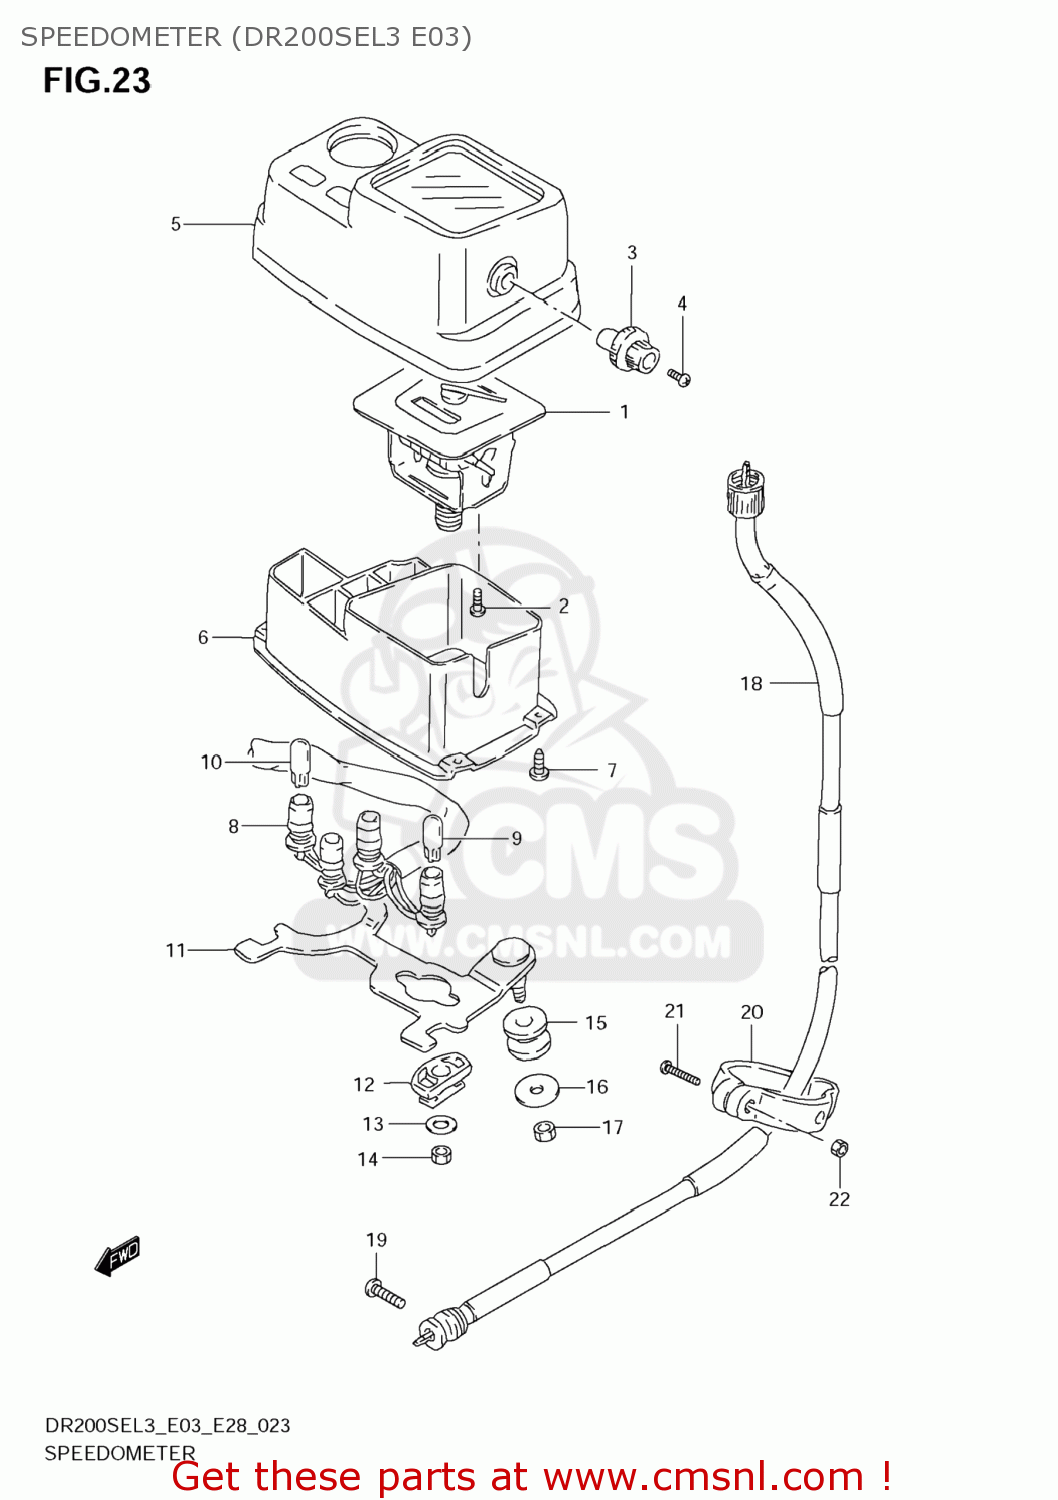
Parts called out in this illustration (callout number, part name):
1	SPEEDOMETER
2	SCREW
3	KNOB,TRIP
4	SCREW(2X6)
5	HOOD,METER
6	CASE,METER
7	SCREW
8	SOCKET ASSY
9	BULB(12V3.4W,T10)
10	BULB(12V1.7W,T10,WB121)
11	BRACKET,METER
12	CUSHION
13	WASHER(5.5X16X1.2)
14	NUT
15	CUSHION
16	WASHER(6.5X18X1.6)
17	NUT
18	CABLE ASSY,SPEEDOMETER
19	SCREW
20	CLAMP,SPEEDOMETER CABLE
21	SCREW
22	NUT
